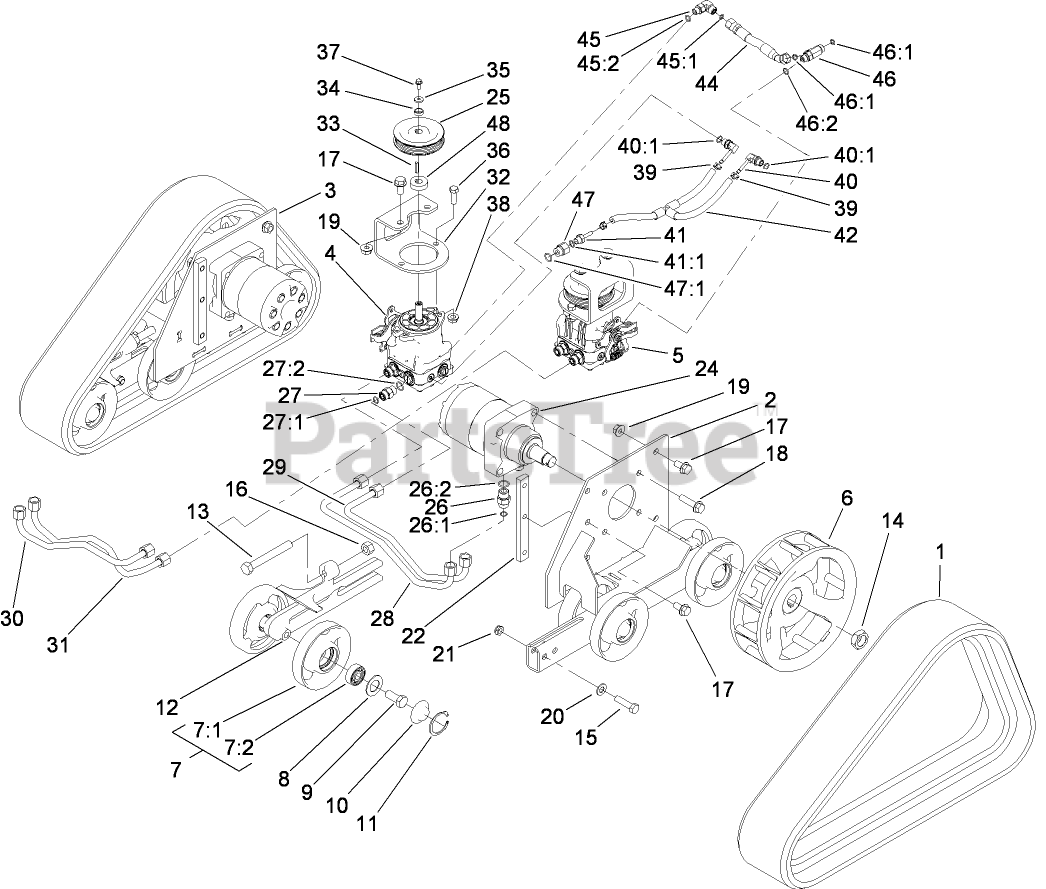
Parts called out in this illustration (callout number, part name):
1	TRACK-RUBBER
2	FRAME-TRACK, LH
3	FRAME-TRACK, RH
4	PUMP-HYD, RH
5	PUMP-HYD, LH
6	WHEEL-DRIVE
7	WHEEL-TENSIONER
7:1	WHEEL-TRACK
7:2	BEARING
8	Gasket-Bogie
9	SCREW-HH
10	CAP-WHEEL, BEARING
11	RING-SNAP, INTERNAL
12	TENSIONER-TRACK
13	SCREW-HH, TAP
14	NUT-LOCK
15	SCREW-HH
16	NUT-HEX
17	SCREW-HHF
18	SCREW-HHF
19	NUT-HHF
20	WASHER-FLAT
21	NUT-LOCK, NI
22	BAR-THREAD
24	HYD WHEEL MOTOR ASM
25	SHEAVE
26	FITTING-STRAIGHT
26:1	O-RING
26:2	O-RING
27	FITTING-STRAIGHT
27:1	O-RING
27:2	O-RING
28	TUBE-HYD
29	TUBE-HYD
30	TUBE-HYD
31	TUBE-HYD
32	BRACKET-MOUNT, PUMP
33	KEY-PUMP
34	BUSHING
35	WASHER
36	SCREW-HH
37	SCREW-HHF
38	NUT-HF
39	Clamp-Hose
40	ELBOW-90 DEG
40:1	O-RING
41	Adapter-Straight
41:1	O-RING
42	HYD HOSE ASM
44	HOSE-HYD
45	FITTING-ELBOW, 90 DEG
45:1	O-RING
45:2	O-RING
46	FITTING-TEE
46:1	O-RING
46:2	O-RING
47	REDUCER-ADAPTER
47:1	O-RING
48	SPACER
